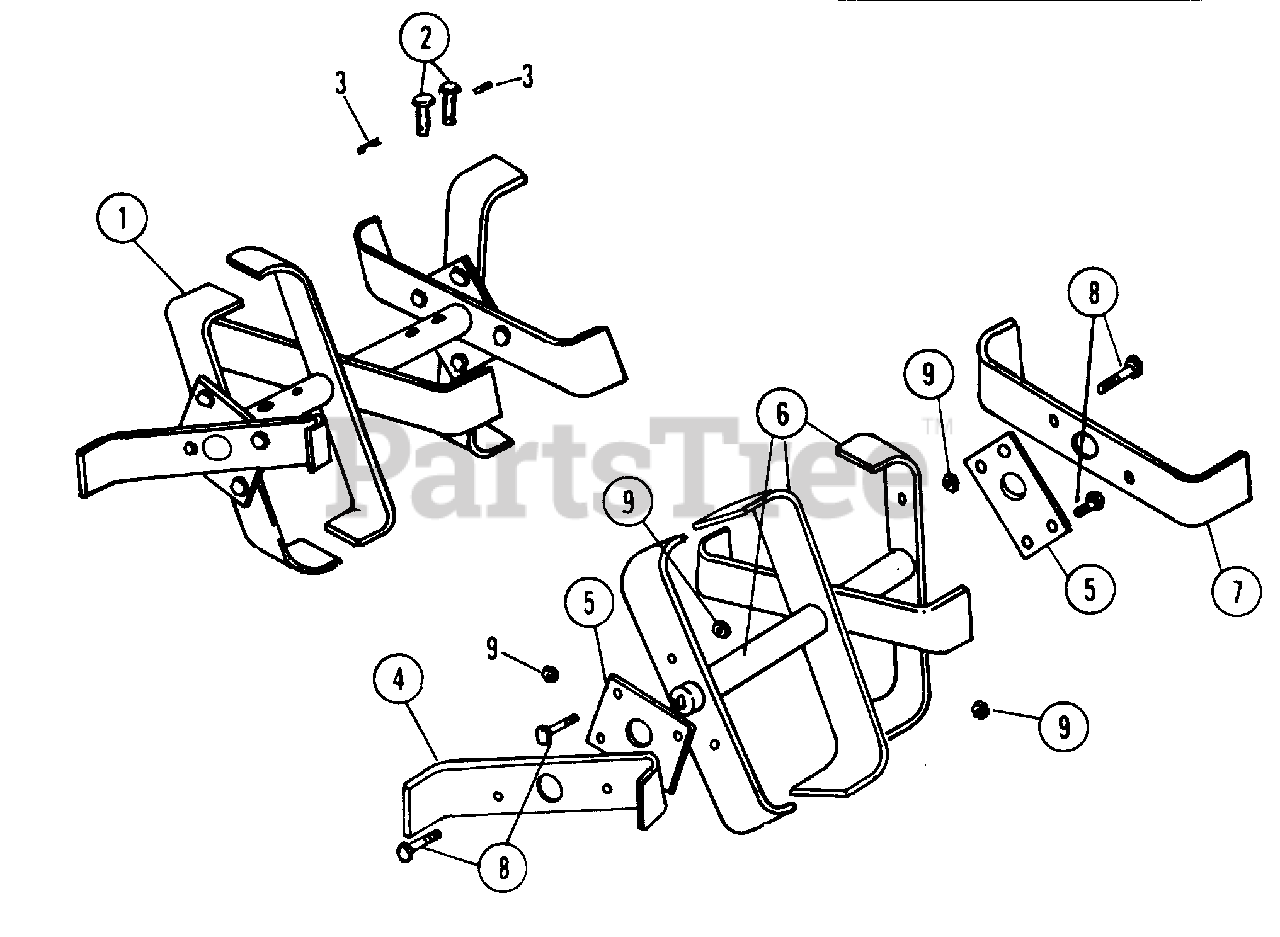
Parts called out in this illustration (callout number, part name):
1	TINE ASSEMBLY
2	PIN, TINE SHEAR 1.75" x .5", .156" Hole
3	PIN, 1/8D x 1 COTTER
4	TINE, LEFT HAND
5	PLATE, TINE ATTACHING
6	TINE-TUBE ASSEMBLY
7	TINE, RIGHT HAND
8	BOLT, 7/16-14 x 1 HEX HEAD
9	LOCKNUT, 7/16-14 HEX
